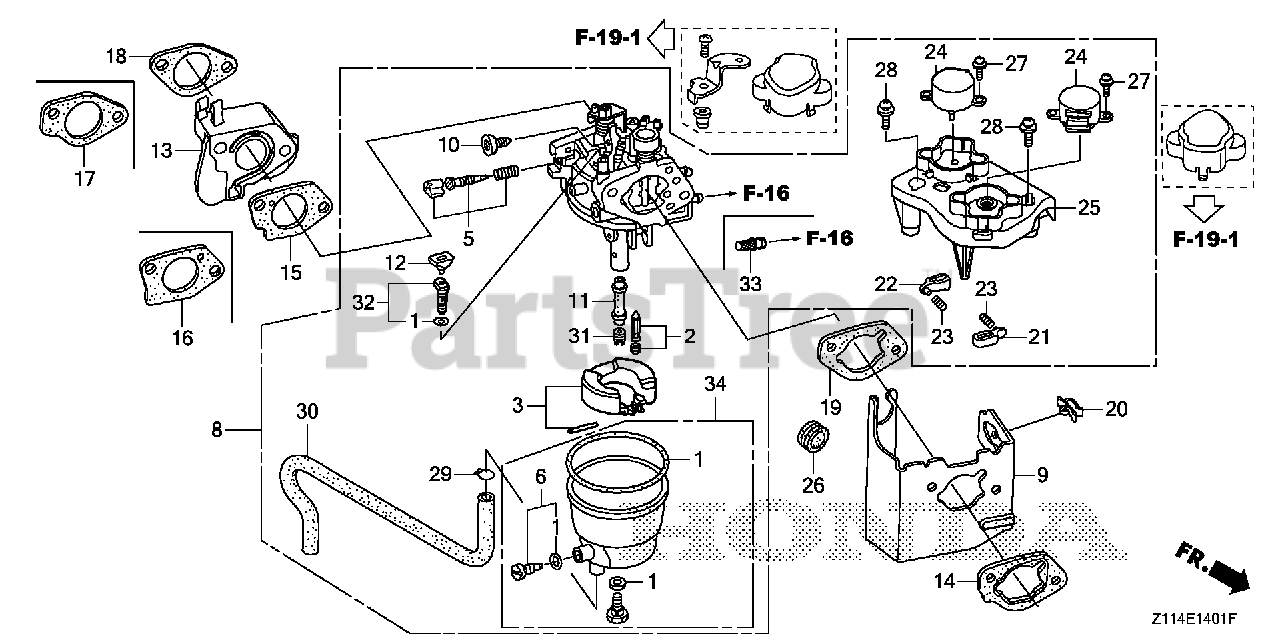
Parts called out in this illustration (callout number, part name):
1	GASKET SET
2	VALVE SET, FLOAT
4	CHAMBER SET, FLOAT
5	SCREW SET, PILOT
6	SCREW SET, DRAIN (CARBURETOR NO.)
7	SCREW SET
8	CARBURETOR ASSY. (BE87Q B/C)
9	HOLDER, TUBE
10	SCREW, STOP
11	NOZZLE, MAIN
12	COLLAR, SETTING
13	INSULATOR, CARBURETOR
14	SPACER, CARBURETOR
16	GASKET, CARBURETOR
17	GASKET, INSULATOR
19	GASKET, AIR CLEANER
20	CLIP B, HARNESS
21	LEVER, LINK
22	LEVER, LINK
23	SPRING, COMPRESSION COIL
24	MOTOR, THROTTLE CONTROL
25	BRACKET, THROTTLE MOTOR
26	GROMMET, FENDER
27	SCREW-WASHER (3X8)
28	SCREW-WASHER (4X12)
29	CLIP, TUBE (C8)
30	BULK HOSE, VINYL (4.5X8X1000) (95003-(95003-09001-60M)
31	JET, MAIN (#92)
31	JET, MAIN (#95)
31	JET, MAIN (#98)
32	JET SET, PILOT (#40)
34	BOLT KIT, FUEL CHAMBER
